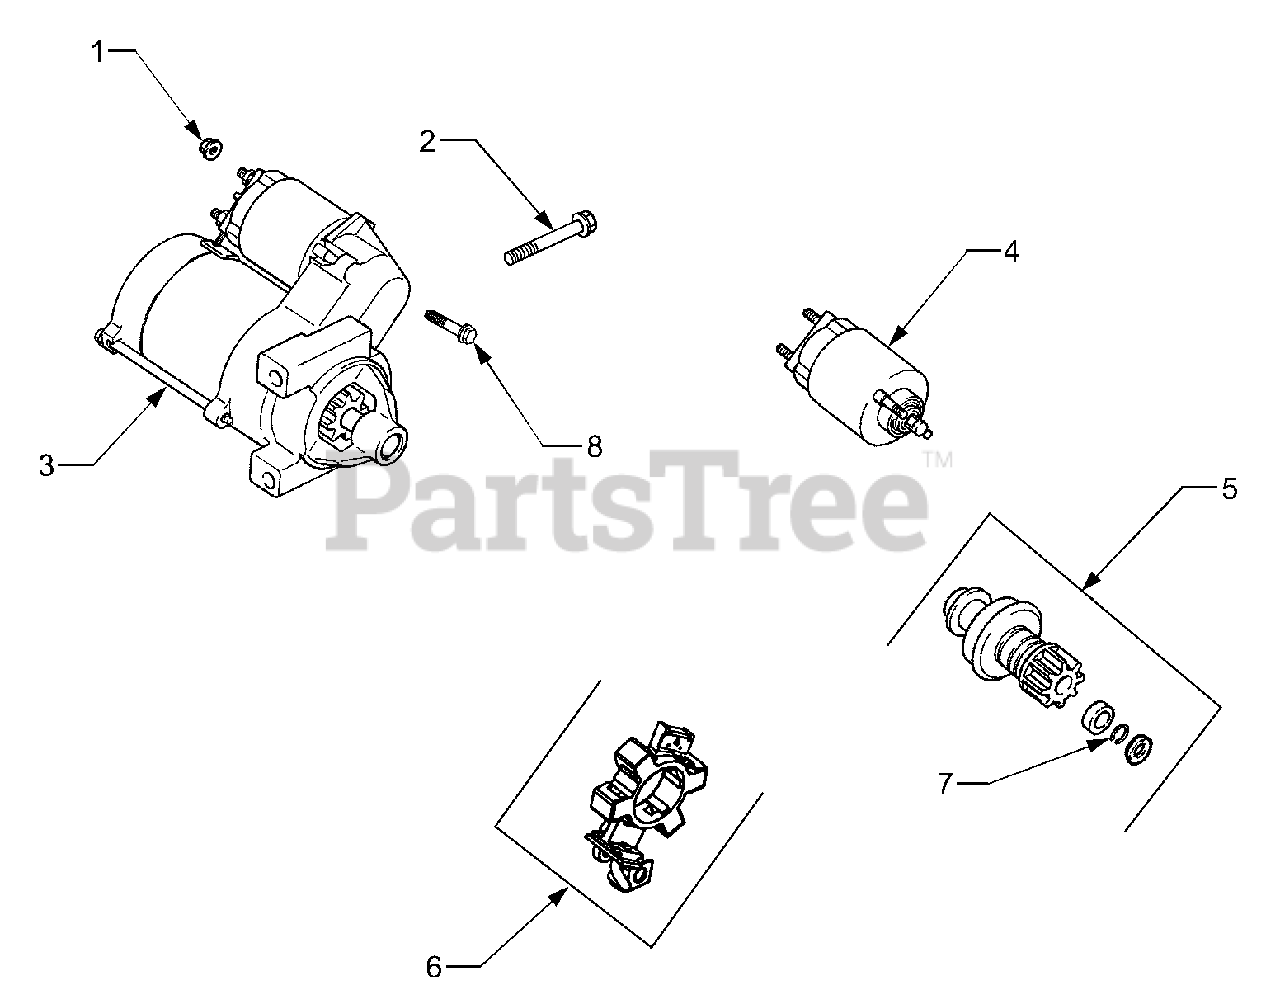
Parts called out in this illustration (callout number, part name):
1	Nut, Hex Flange M8 x 1.25"
2	Screw, Hex Flange M8 x 1.25 x 80
3	Starter, Solenoid Shift Assembly
4	Kit, Solenoid
5	Kit, Pinion Drive
7	Ring, Retainer
8	Screw, External Torx Hd.
